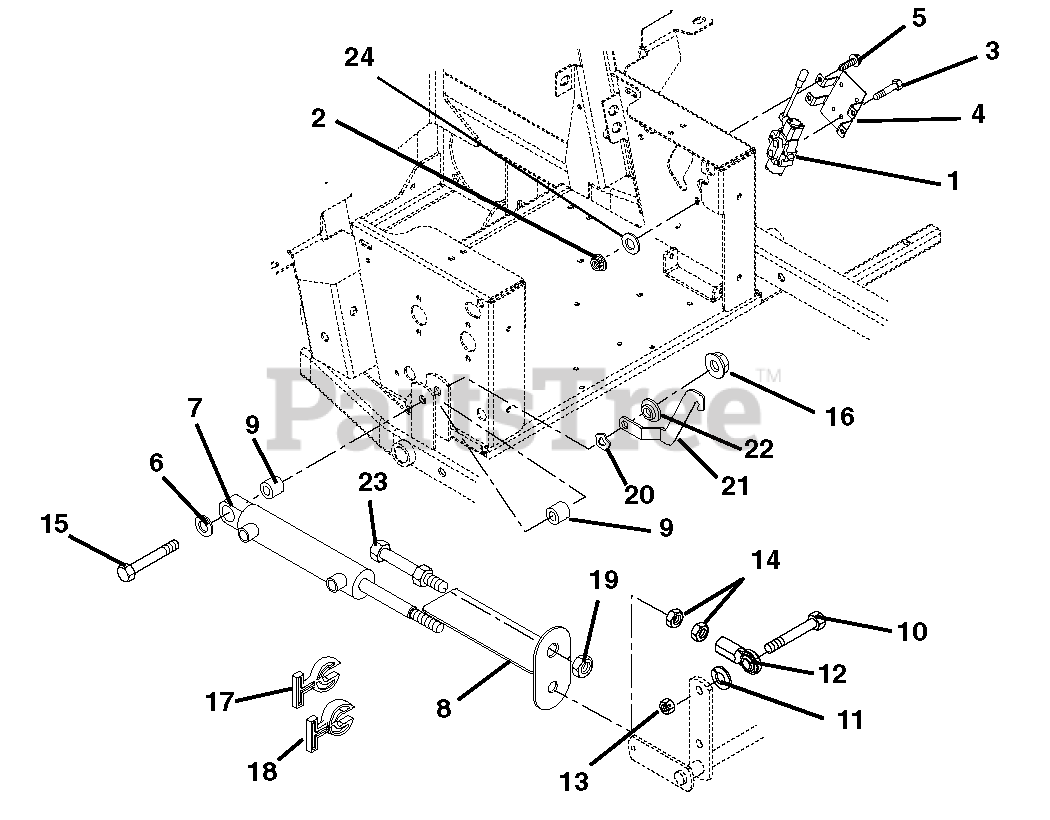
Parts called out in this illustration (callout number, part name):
1	Valve, Hydraulic
2	Nut, Locking Center .31-18
3	Bolt, Hex .31-18 x 2.00 Grade 5
4	Bracket, Valve Mounting
5	Screw, Tapping .38-16 x .50 Hex Washer Head
6	Washer, Flat-Steel .515 x 1.625 x .25
7	Cylinder, Lift
8	Strap, Height of Cut Indicator
9	Bushing .516 x 1.00 x 1.05
10	Bolt, Hex .62-11 x 2.25 Grade 8
11	Washer, Lock .62 x .156
12	Rod End, Right Hand Female .625
13	Nut, Locking Center .62-11
14	Nut, Jam .625-18
15	Bolt, Hex .50-13 x 3.75 Grade 5
16	Nut, Locking Top Flange .50-13
17	Stop, Cylinder .34 Thick
18	Stop, Cylinder .68 Thick
19	Nut, Jam .75-16
20	Washer, Wave .076 x 1.12 x .08
21	Latch, Floor Board
22	Bushing, Flange .515 x .75 x .275 x 1.12
24	Washer, Lock .31 x .078 Reg
